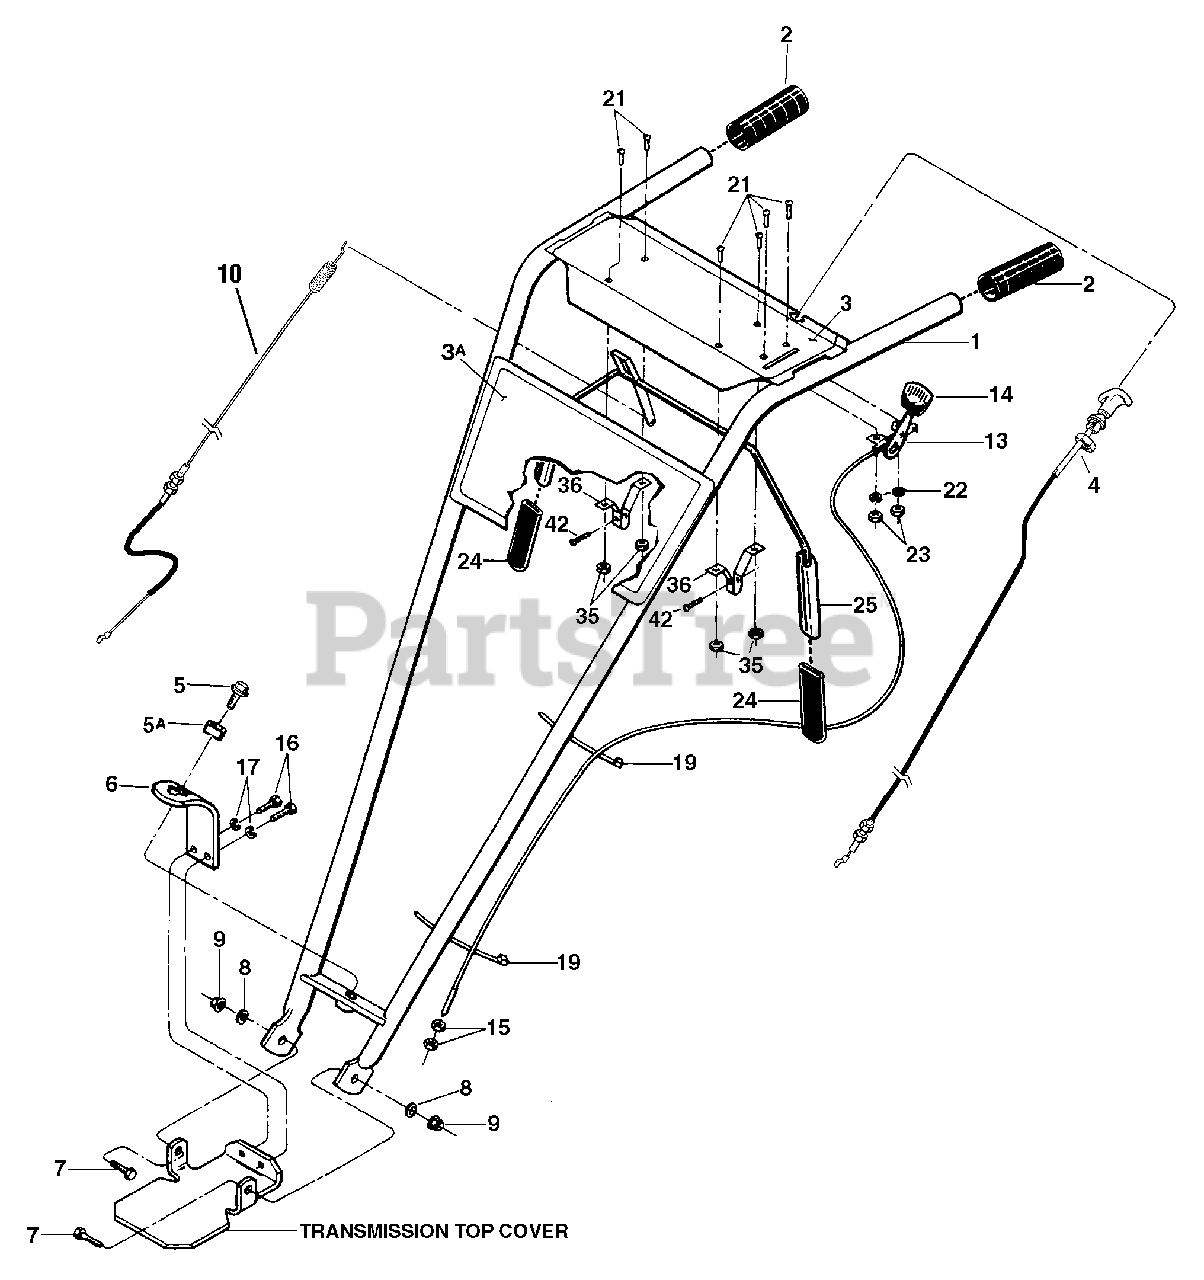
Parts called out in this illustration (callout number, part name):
1	Handlebars
2	Grip
3	Decal-Operator control panel
3A	Decal-Logo
4	Reverse Clutch Cable Assembly
5	Height Adjustment Flange Screw
5A	Keyed Washer
6	Bracket-Handlebar height adjust
7	Hex Hd. Screw, 3/8-16 x 1
8	Plain Washer (flat), 3/8, S.A.E.
9	Hex Locknut, 3/8-16
10	Cable, Forward Clutch Control
13	Wheel Gear Control & Cable Assy.
14	Knob-Wheel gear control lever
15	Hex Nut, 5/16-24-Wheel gear cable adjustment
16	Hex Hd. Screw, 3/8-16 x 3/4
17	Lockwasher, 3/8
19	Plastic Tie
21	Round Hd. Screw, #10-32 x 1/2
22	Lockwasher, #10
23	Hex Nut, #10-32
24	Grip-Lever
25	Lever-Forward Clutch Control
36	Bracket-Bail support
42	Hex Flange Screw, self-tapping, 1/4-20 x 1/2
